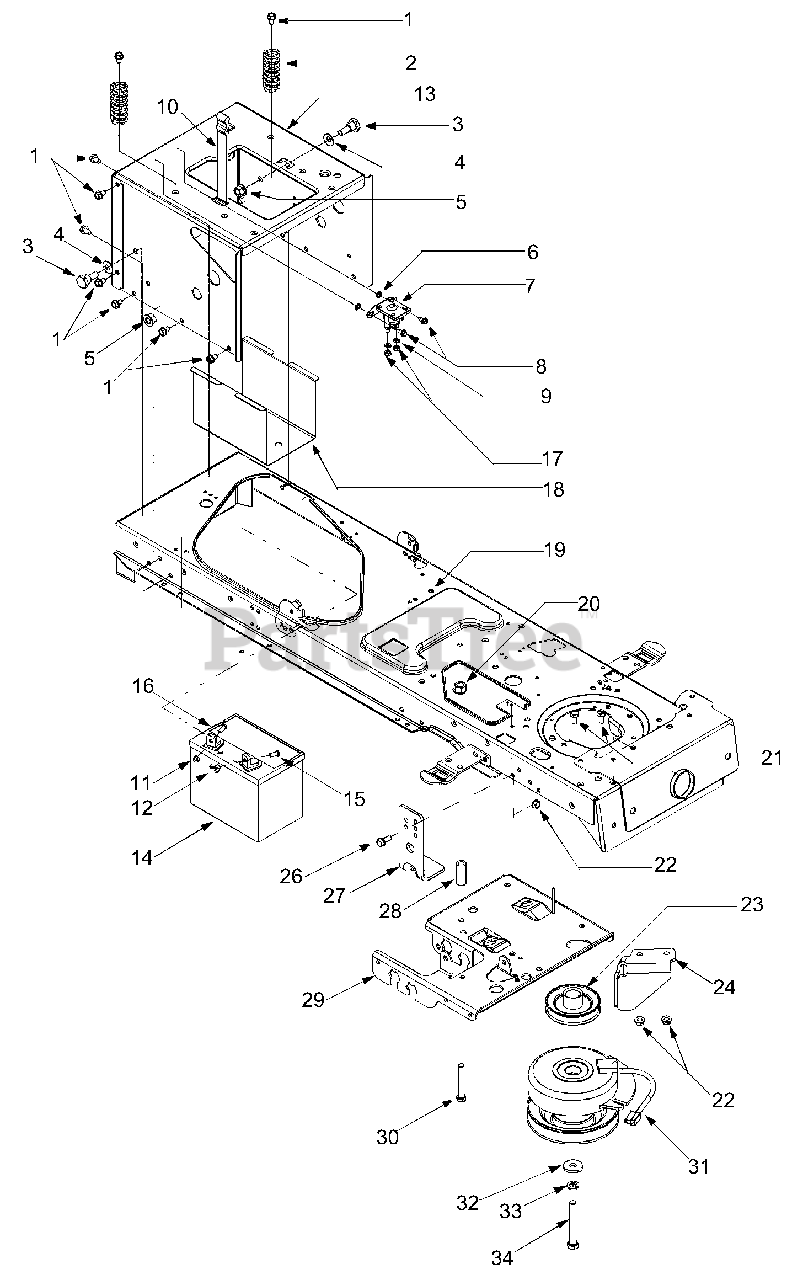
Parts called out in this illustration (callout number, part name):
1	TT Screw 5/16-18 x 0.625"
2	Compression Spring
3	Shoulder Screw 0.625 x 0.5
4	Bell Washer
5	Flange Lock Nut
6	Lock Washer, 1/4
7	Solenoid: 12 V., 100 amp.
8	TT Screw 1/4-20 x 0.5"
9	Lock Washer, 1/4
10	Battery Strap
11	Hex Sems Nut 1/4-20
12	Wing Nut
15	Shoulder Screw
16	Carriage Screw 1/4-20 x 0.75"
17	Hex Nut 1/4-20
21	Hex Screw 5/16-18 x 0.625
22	Flange Lock Nut 5/16-18
23	Engine Pulley: Electric PTO
28	Spacer
30	Hex Screw 3/8-16 x 2.5"
31	Elec. PTO Clutch
31	Washer, Flat 1.031 x 1.62 x .095
32	Flat Washer
33	Lock Washer
34	Hex Bolt 7/16-20 x 3.25"
